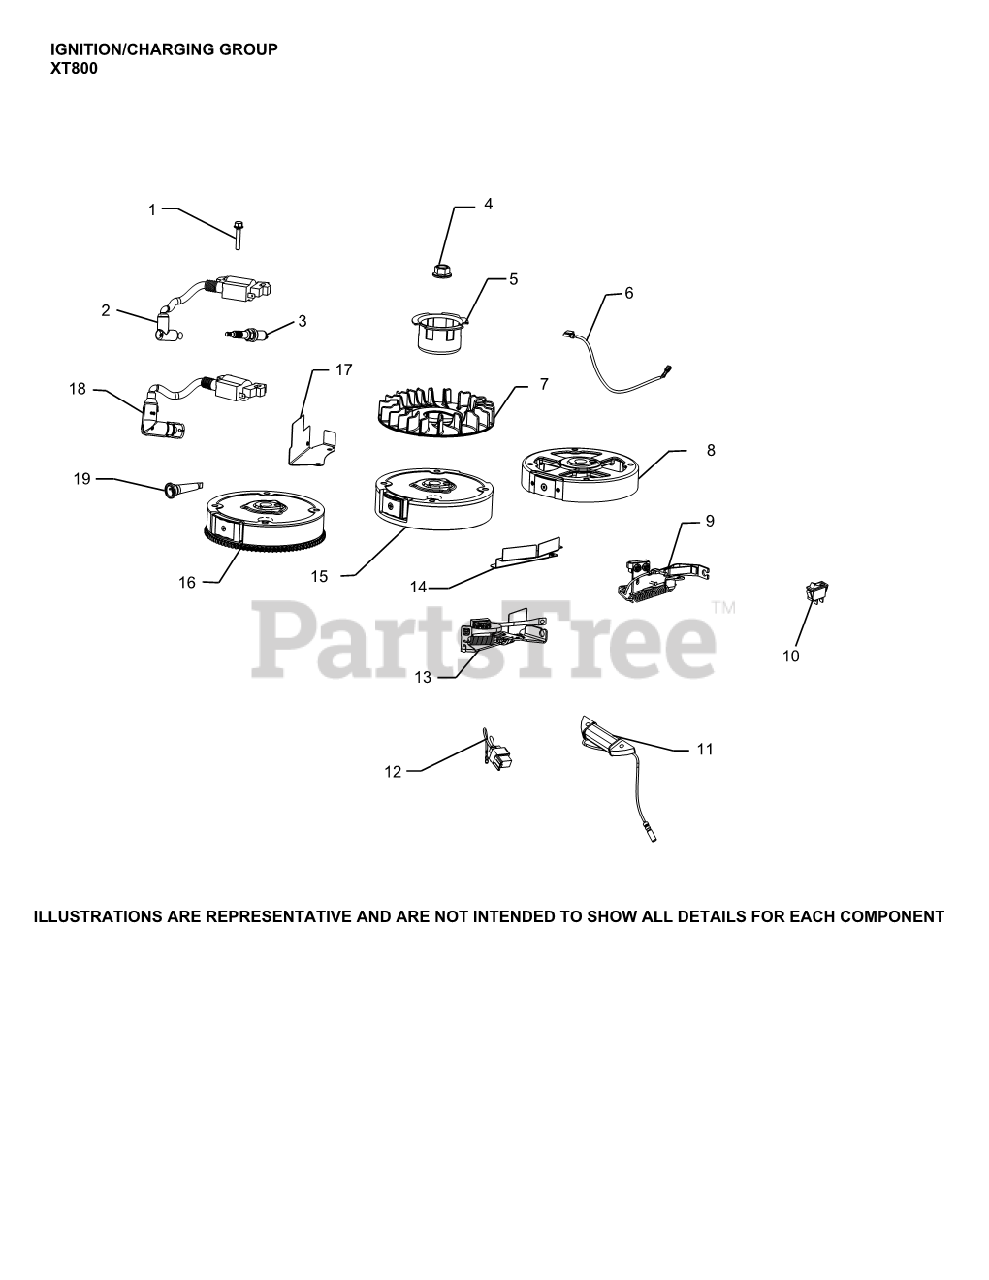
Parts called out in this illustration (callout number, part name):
1	SCREW, M6 X 25 USE 25 086 436-S
2	MODULE,IGN (CAST IRON,STD IGN) USE 14 584 16-S
3	PLUG, SPARK 12MM RFI
4	NUT, FLYWHEEL (W/SERRATIONS)
5	CUP, STARTER DRIVE
7	FAN, FLYWHEEL
8	FLYWHEEL ASSEMBLY, CAST IRON USE 14 025 12-S
13	BRAKE, ASSEMBLY USE 14 219 17-S
17	GUARD, FINGER
